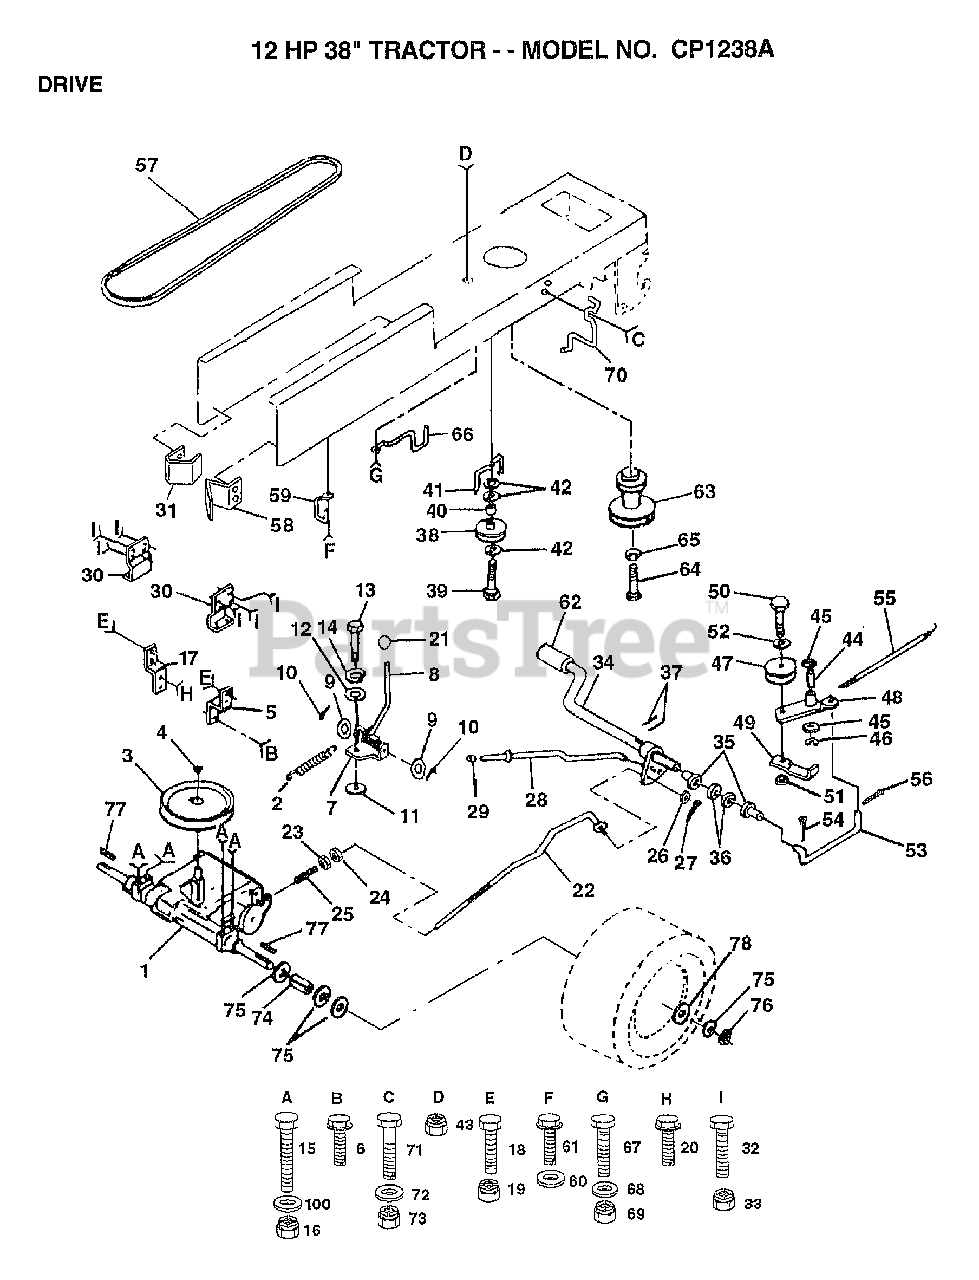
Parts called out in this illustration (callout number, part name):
3	PULLEY TRANS
5	STRAP TORQUE
6	SCREW
7	PLATE SHIFT LT
8	ROD SHIFTER
9	WASHER
10	PIN COTTER 1/8
11	WASH-SHFT PLT LT
12	WASHER LT
14	LOCKWASHER
15	BOLT
17	STRAP TORQUE
20	SCREW
21	KNOB T (1/2-HOLE)
23	NUT
24	NUT
25	SPRING ROD LT
26	WASHER
27	COTTER PIN
28	PARKING BRAKE ROD
29	PLUNGER CAP T
30	BRACKET LT
31	"KEEPER,BELT LH T"
32	BOLT
35	NYLON BEARING
36	WASHER LT
38	PULLEY.IDLER.FLAT
39	BOLT
40	SPACER T
41	BELT KEEPER LT
42	WASHER
44	"LY, BEARING"
45	WASHER LT
46	KLIP RING
48	ARM IDLER
49	RETAIN BELT
52	WASHER
53	"LINK, CLUTCH T"
54	COTTER PIN
55	"SPRING, RETURN LT"
56	COTTER PIN
57	BELT-V.90.0.GD.DR
58	"KEEPER,BELT RH T"
60	WASHER
61	SCREW
62	PEDAL COVER T
64	BOLT
65	LOCKWASHER
66	KEEPER.BELT.ENG.L
67	BOLT
68	WASHER
70	KEEPER BELT ENG
71	BOLT
72	WASHER
74	SPACER LT
75	WASHER
76	E-RING LT
77	SQUARE KEY
78	WASHER
100	WASHER
